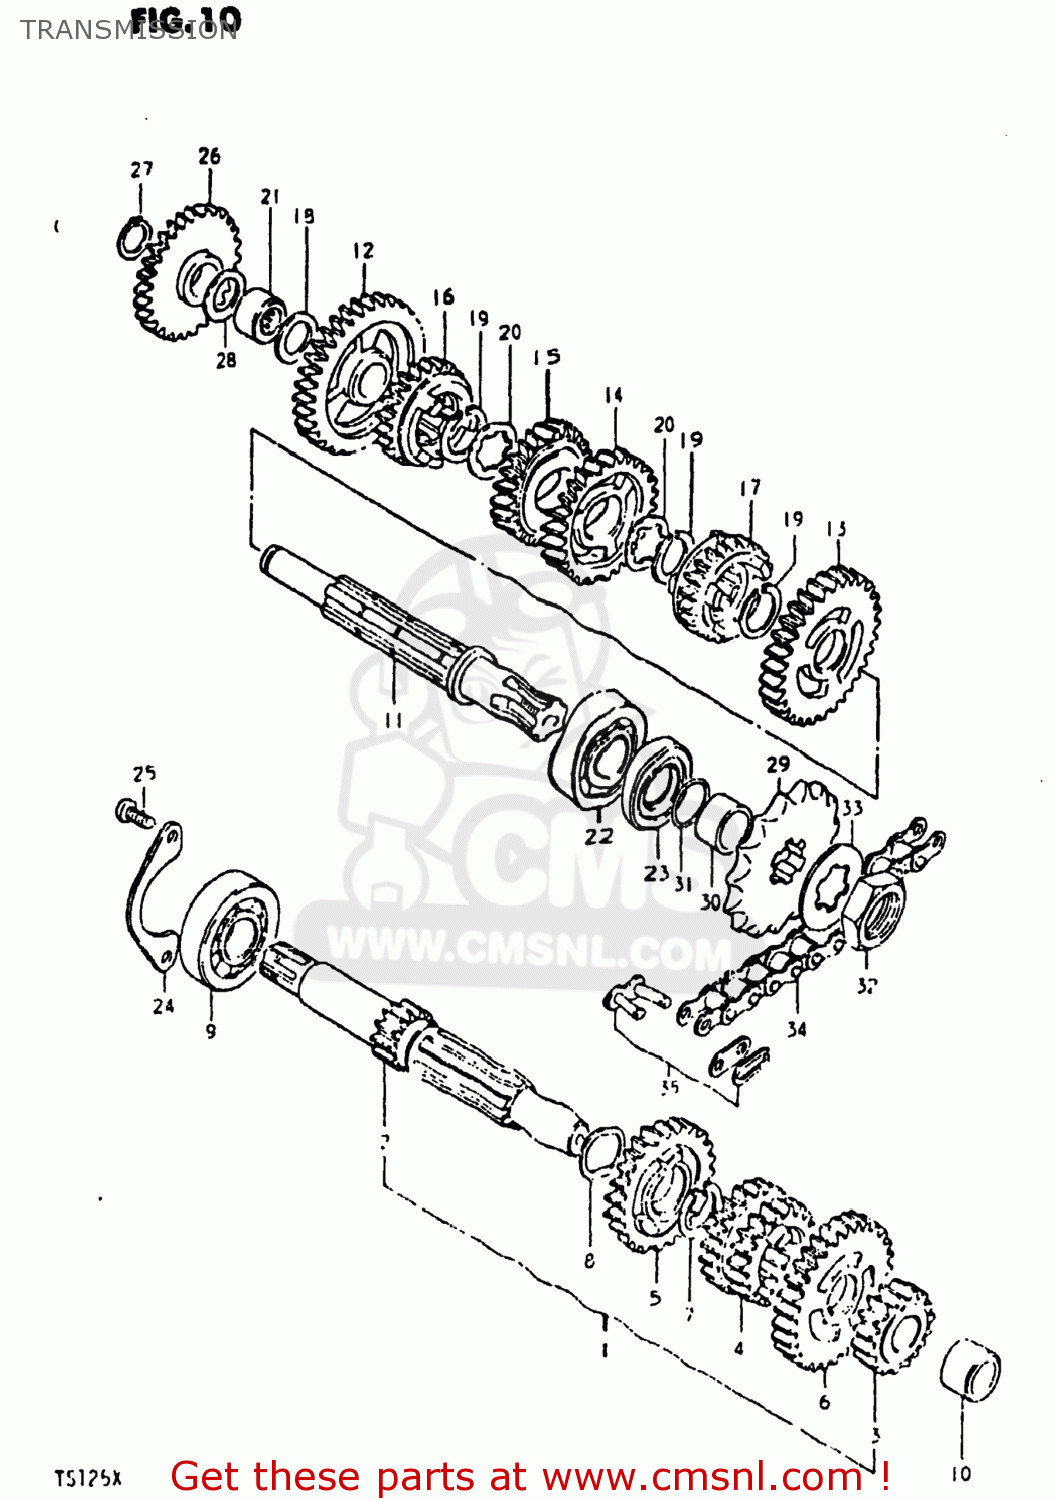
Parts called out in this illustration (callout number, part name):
1	SHAFT ASSEMBLY,COUNTER
2	SHAFT,COUNTER
3	GEAR,SECOND DRIVE
4	GEAR,THIRD/FOURTH DRIVE
5	GEAR,FIFTH DRIVE
6	GEAR,SIXTH DRIVE
7	CIRCLIP
8	WASHER
9	Bearing
10	BUSH(15X22X15)
11	SHAFT,GEAR SHIFT
12	GEAR,1ST DRIVEN
13	GEAR,SECOND DRIVEN
14	GEAR,THIRD DRIVEN
15	GEAR,FOURTH DRIVEN
16	GEAR,FIFTH DRIVEN
17	GEAR,SIXTH DRIVEN
18	WASHER,THRUST
19	CIRCLIP
20	WASHER,LOCK
21	BEARING(15X22X12)
22	Bearing
23	SEAL,OIL(25X40X7)
24	RETAINER,CNTR SHAFT BEARING
25	SCREW 6X12
26	GEAR,KICK STARTER IDLE
27	CIRCLIP,15MM
28	WASHER,THRUST
29	SPROCKET,ENGINE
30	SPACER(20X25X12.5)
31	O RING(D:1,ID:19.5)
32	NUT
33	WASHER,LOCK
34	CHAIN ASSEMBLY,DRIVE
35	JOINT ASSEMBLY,CHAIN
